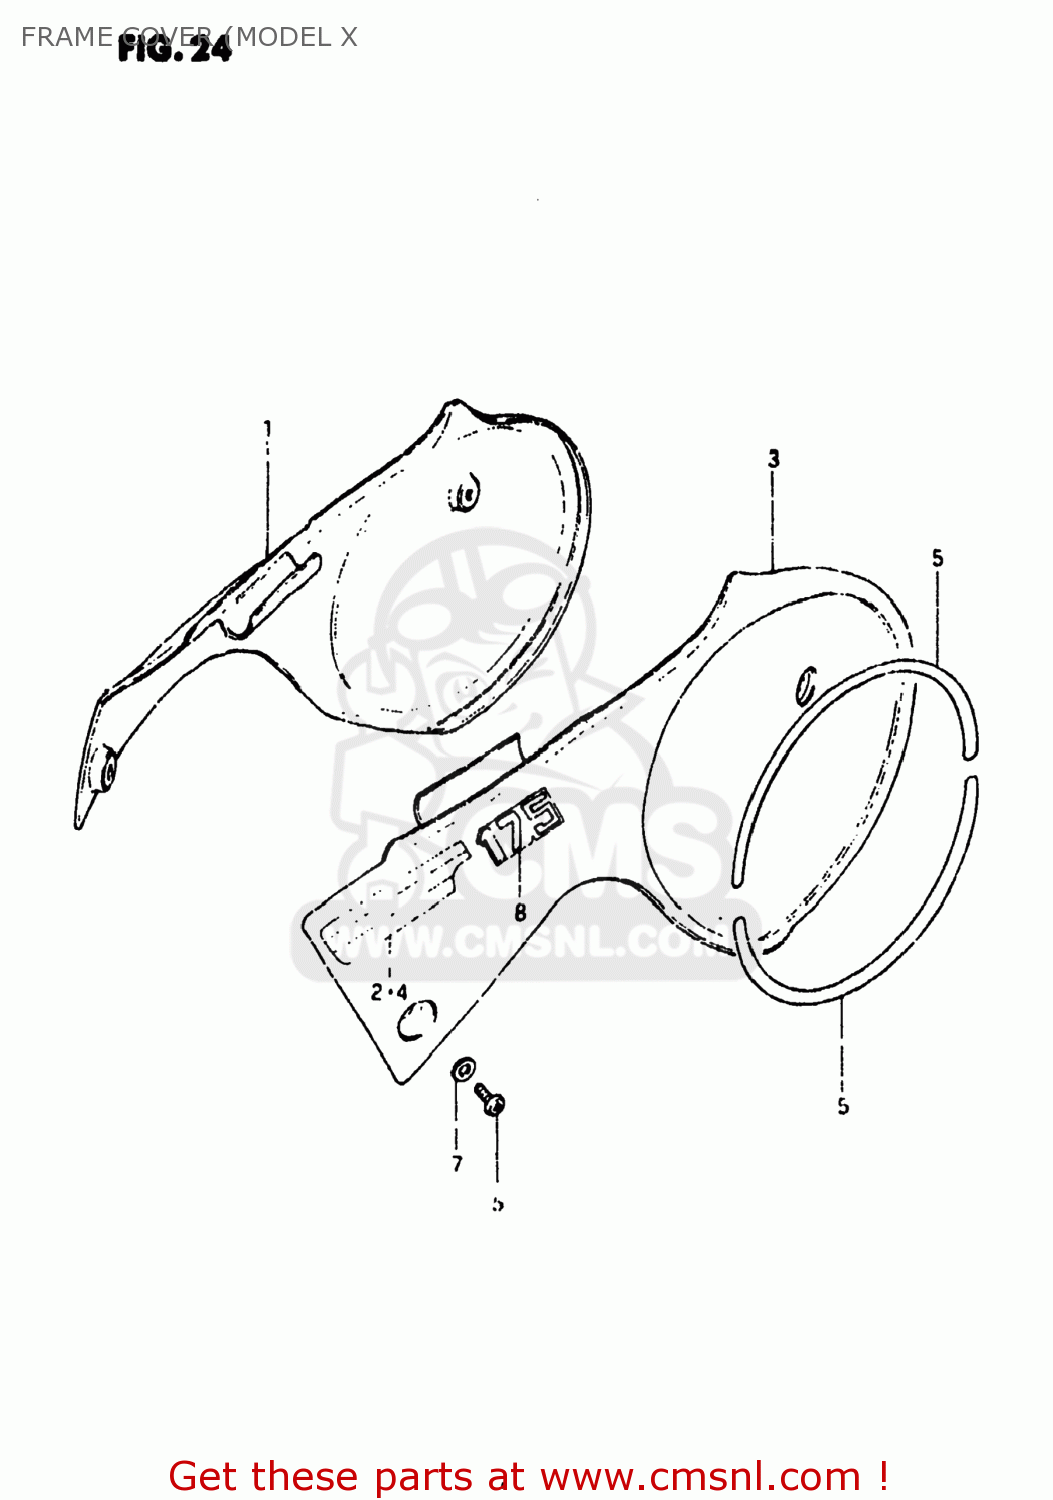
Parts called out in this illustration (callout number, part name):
1	COVER,FRAME,R(YELLOW)
2	TAPE,FRAME COVER,RIGHT
3	COVER,FRAME,L(YELLOW)
4	TAPE,FRAME COVER
5	TAPE,FRAME COVER
6	SCREW
7	WASHER
8	EMBLEM (175)
